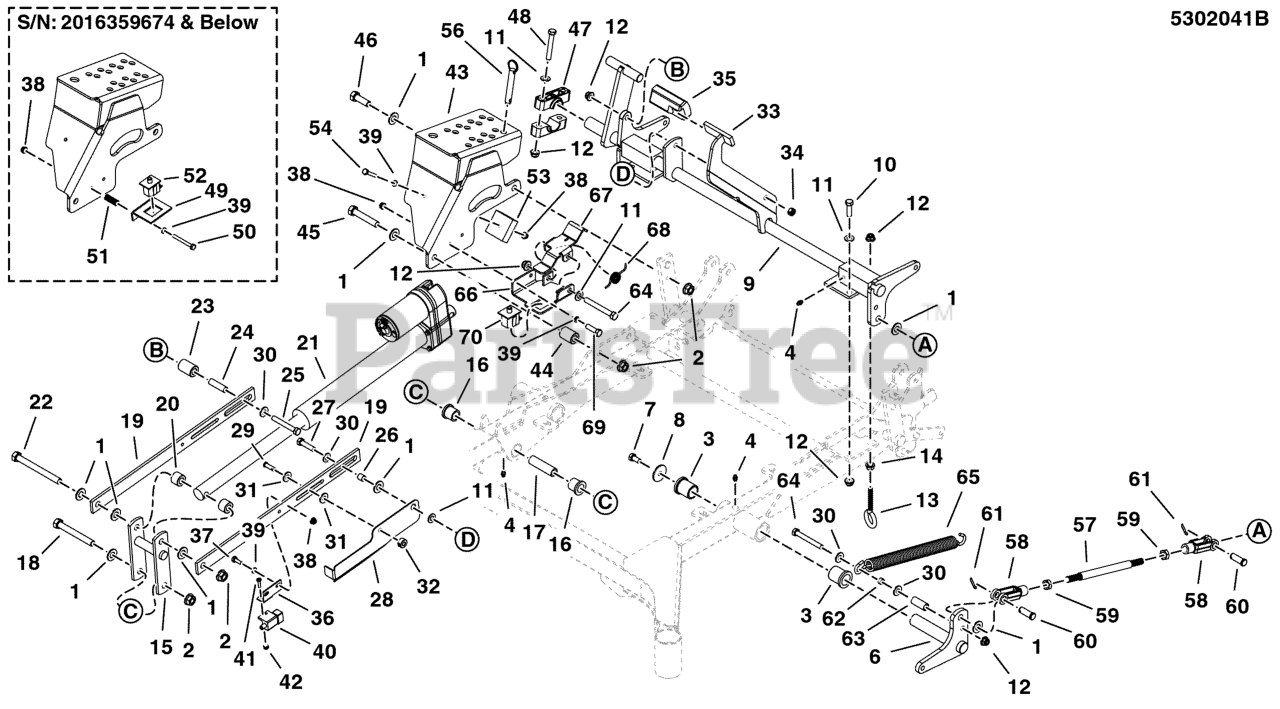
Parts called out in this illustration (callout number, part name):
1	WASHER, 1/2 SAE
2	NUT, Hex Flange, Nylock, 1/2-13
3	BUSHING, FLANGE
4	GREASE FITTING, 1/4-28 STRAIGHT
6	WELD., DECK LIFT LEVER - LH - RED
7	BOLT, 3/8-16 X 3/4, PLT W/PATCH
8	WASHER, .390 X 1.50 X .109, YZ
9	WELD, DECK LIFT SHAFT - OUTFRONT - RED
10	BOLT, 3/8-16 X 1-1/4" GD5 CZ
11	WASHER, 3/8 SAE
12	NUT, 3/8-16 HEX NYLOCK FLANGE
13	EYEBOLT, 3/8-16 X 4, 2.13THRD, .75EYE, C
14	NUT, 3/8-16 HEX SERRATED FLANGE
15	WELD, PIVOT LINK - ACTUATOR - RED
16	BUSHING, FLANGED, 3/4 X 1 X 1
17	SPACER, .51 X .75 X 2.66
18	BOLT, 1/2-13 X 4" GD5 CZ
19	BAR, ACTUATOR LINK - RED
20	SPACER, .52 X 1.00 X .75, CZ
21	ACTUATOR, 12" STROKE, 1600 LBS
22	BOLT-1/2-13 X 5 GD5 YZ
23	SPACER, .51 X 1.00 X 1.47 CZ
24	SPACER, .38 X .50 X 1.78
25	BOLT, 3/8-16 X 2-3/4" GD5 CZ
26	SPACER, .38 X .50 X .50
27	BOLT, 3/8-16 X 1-1/2" GD5 CZ
28	PLATE, SWITCH COVER - RED
29	PIN-CLEVIS, 5/16 X 1 YZ
30	WASHER, 5/16 USS
31	WASHER, 5/16" SAE
32	COLLAR, 5/16 SET
33	WELD, DECK LIFT PEDAL - RED
34	NUT, 3/8-16 HEX SIDE LOCK
35	PEDAL, Rubber
36	PLATE, SWITCH MOUNT - RED
37	BOLT, 1/4-20 X 3/4 GD5 YZ
38	NUT, 1/4-20 HEX NYLOCK FLANGE
39	WASHER, 1/4 SAE
40	SWITCH, PLUNGER, N.O./N.C.
41	SCREW, #10-24 X 3/4 ROUND PHILLIPS
42	NUT, #10-24 HEX NYLON LOCK
43	WELD, CUT HEIGHT BOX - RED
44	SPACER, .52 X 1.00 X 1.38 CZ
45	BOLT, 1/2-13 X 2-3/4 GD5 CZ
46	BOLT, 1/2-13 X 1-1/2 GD5 CZ
47	PIVOT BLOCK, PLASTIC
48	BOLT, 3/8-16 X 2-1/2" GD5 CZ
49	MOUNT, LOW PROFILE SWITCH - RED
50	BOLT, 1/4-20 X 2-1/4, GD5
51	SPRING-COMP,.335IDX1.250LGX.070WR - BLK
52	SWITCH, LOW PROF, NC/NO
53	FLASHER, 90 FPM, OUT FRONT MOWER
54	BOLT, 1/4-20 X 1-1/2, GD5
56	PIN-COTTERLESS
57	ROD, DECK LIFT, OUTFRONT
58	CLEVIS, 1/2-20, STEEL, CLEAR ZINC
59	NUT, 1/2-20 HEX JAM
60	CLEVIS PIN, 1/2 X 1.36 SAE STANDARD
61	PIN, 3/32 X .750, COT, ZINC/CLEAR
62	SPACER, .38 X .50 X .27, CZ
63	SPACER, .39 X .63 X 1.50, CZ
64	BOLT, 3/8-16 X 3" GD5 CZ
65	SPRING-EXT, 1.00 ODX13.25LGX.177WR, BLK
66	WELD, SWITCH MOUNT - BLK
67	INDICATOR, DECK POSITION - BLK
68	SPRING, TORSION, .591ID X .40LG X .95WR
69	BOLT, 1/4-20 X 1" GD5 CZ
70	SWITCH, LOWER PRO, NC/NC
